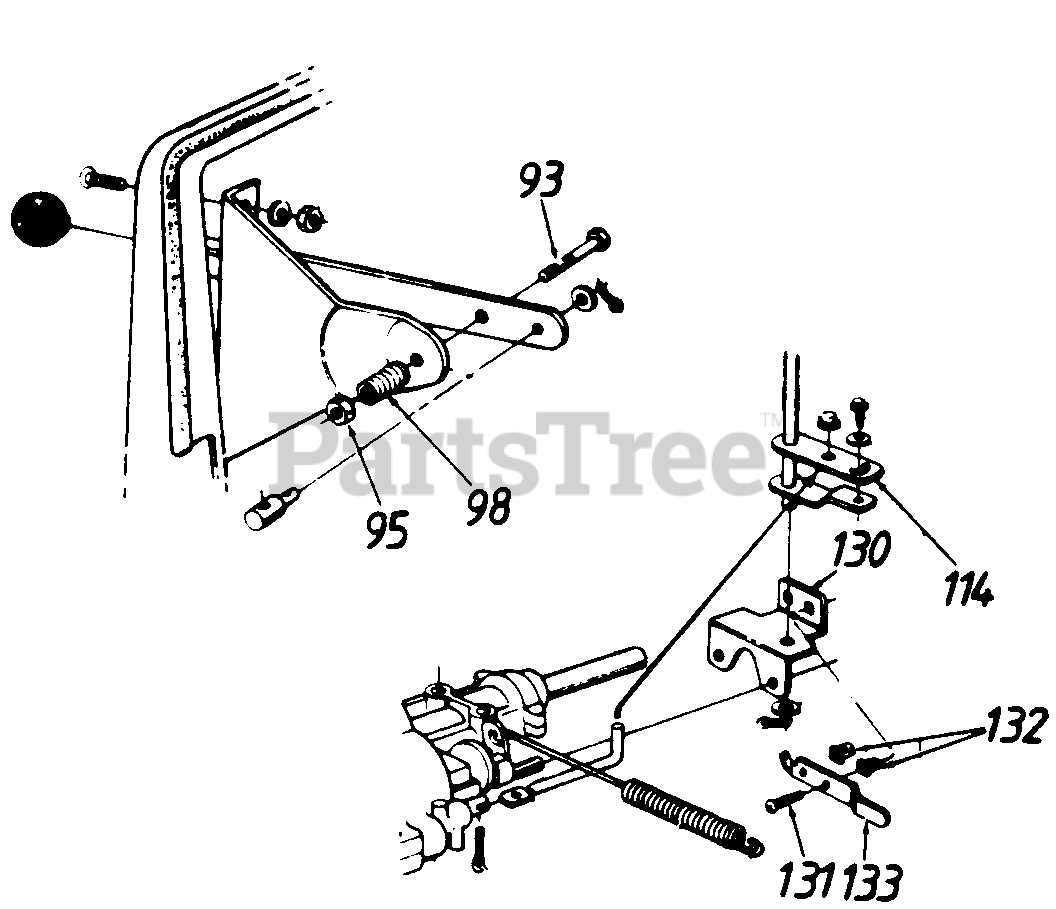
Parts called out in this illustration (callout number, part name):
93	Hex Bolt 1/4-28 x 1.5" Lg.
95	Hex L-Nut 1/4-28 Thd.
98	Comp. Spring 1" Lg.
114	Shift Lever Adjusting Link
130	Shift Lever Support
131	Countersunk AB-Tap Scr. #8 x .5" Lg.
132	Push Nut
133	Spring Switch
